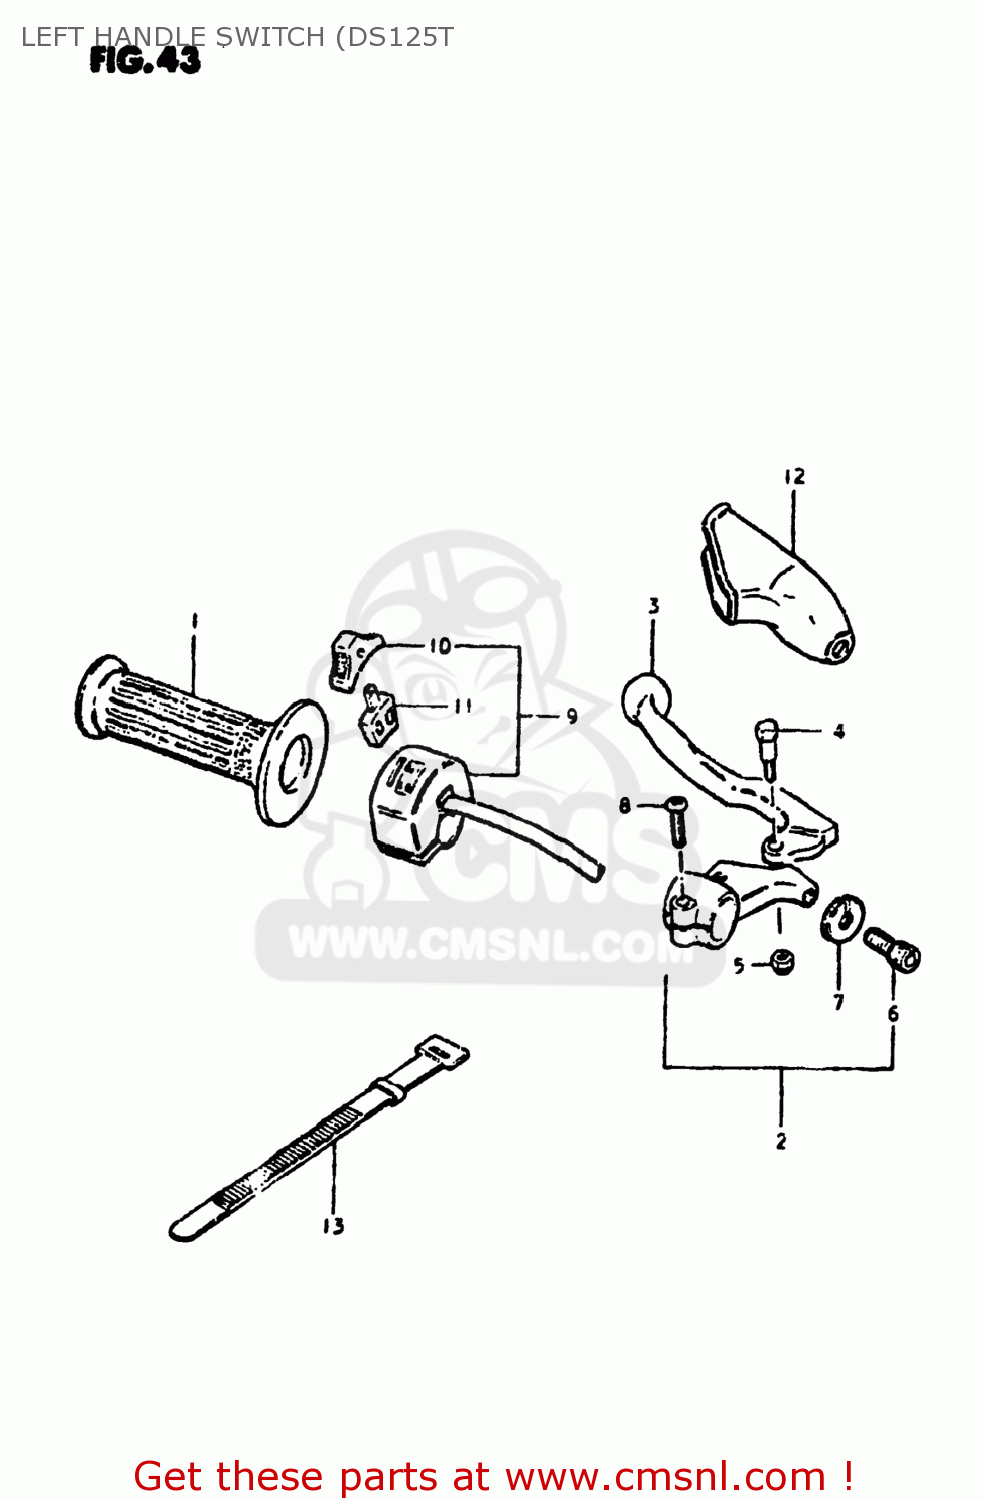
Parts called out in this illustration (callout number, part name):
1	GRIP,L
2	LEVER ASSEMBLY,CLUTCH
3	LEVER,CLUTCH
4	BOLT,LEVER
5	NUT 6MM
6	ADJUSTER,CABLE
7	NUT,CABLE ADJUSTER
8	SCREW
9	SWITCH,DIMMER
10	KNOB,LIGHTING & DIMMER
11	BLOCK,LIGHTING/DIMMER
12	COVER,CLUTCH LEVER
13	CLAMP(L:120)
